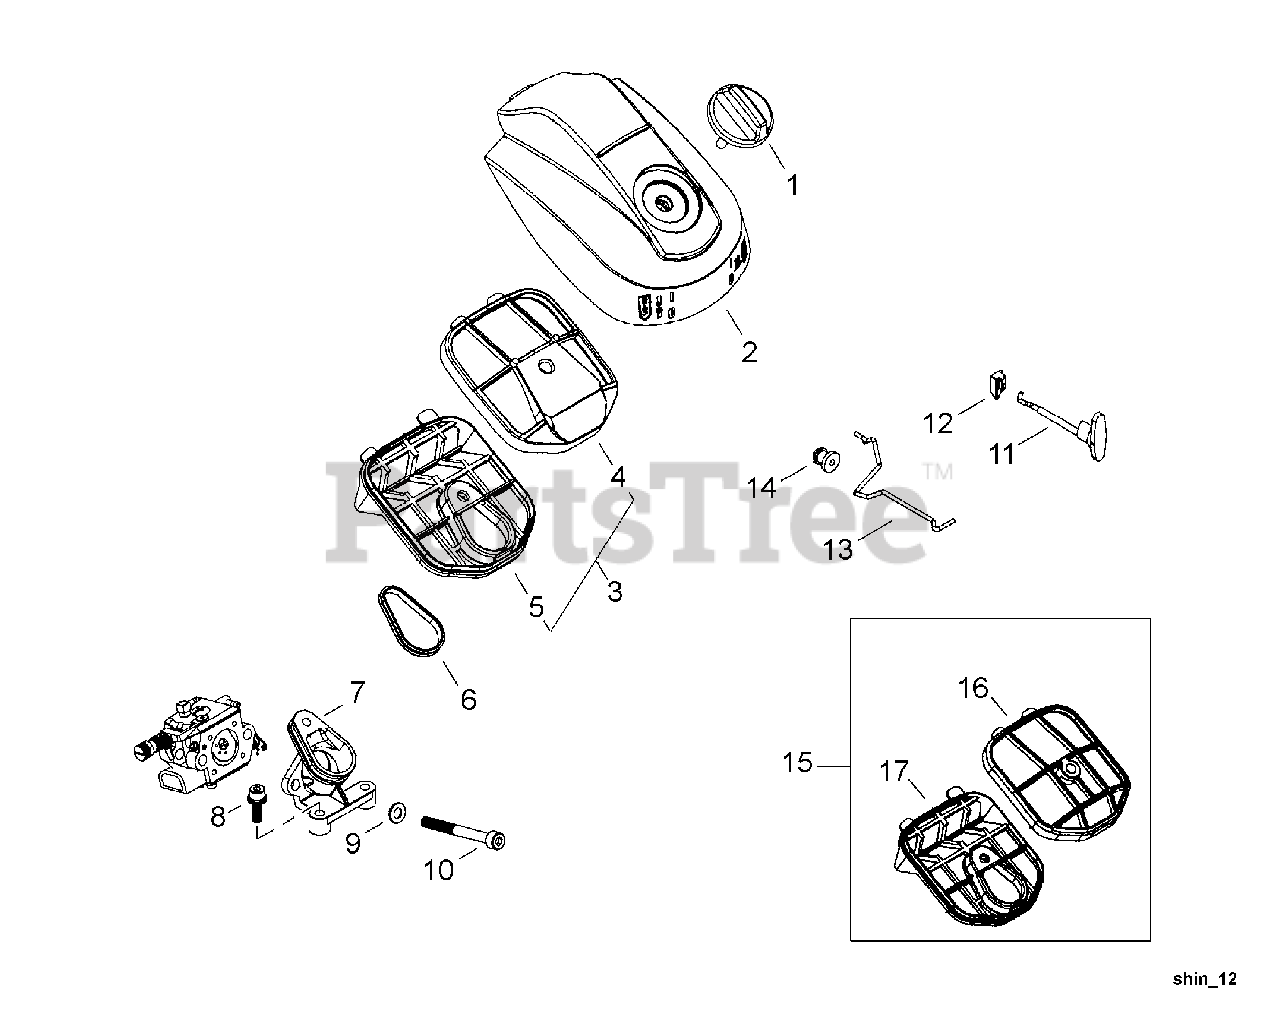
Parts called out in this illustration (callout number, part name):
1	THUMBSCREW
2	COVER, AIR FILTER
3	AIR FILTER ASSY
4	FILTER, AIR - UPPER -- MESH
5	AIR FILTER - LOWER
6	GASKET
7	ADAPTER, AIR FILTER
8	SCREW - 4X16
9	WASHER - 5
10	SCREW - 5X48
11	ROD, CHOKE
13	ROD, THROTTLE
14	GROMMET
15	AIR FILTER KIT
16	FILTER, AIR - UPPER -- FLOCKED
17	FILTER, AIR - LOWER -- FLOCKED
